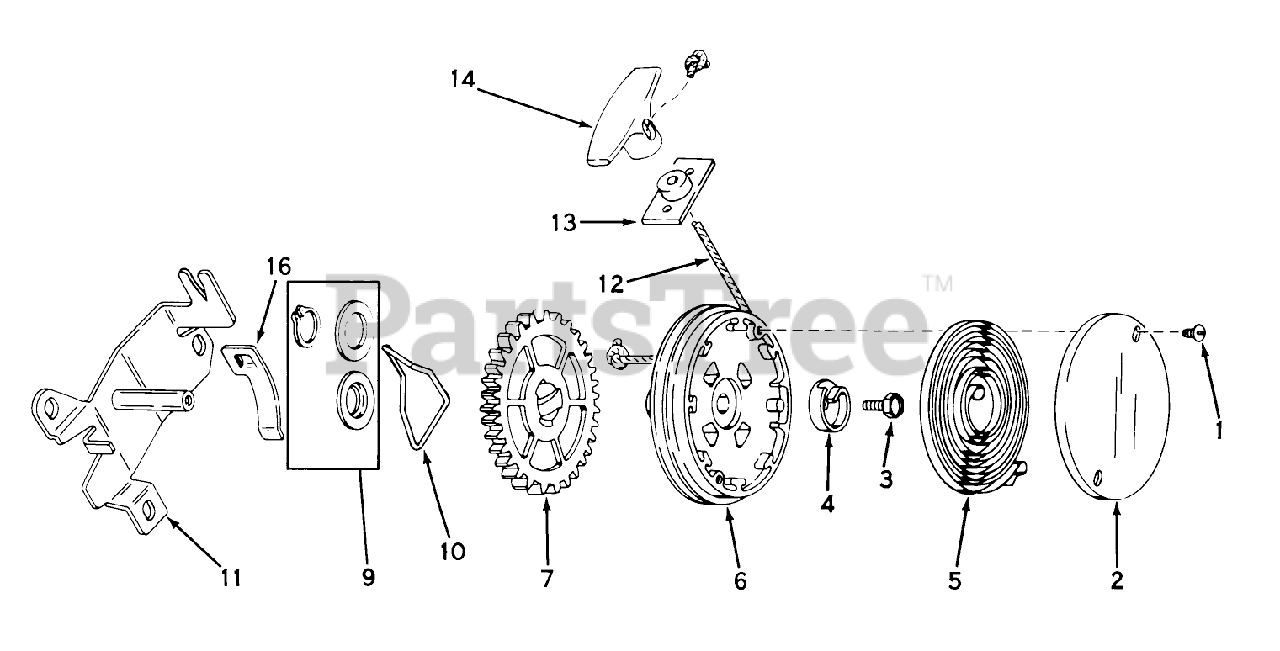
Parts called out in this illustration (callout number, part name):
1	Screw, Cover
2	Cover, Spring
3	Screw, Hex Washer Head
4	Hub Spring
5	Spring, Rewind
6	Pulley Assy. (Incl. No. 9)
9	Kit, Thrust Wash. Snap Rg.
10	Brake
11	Bracket Assy. Mounting
12	Rope, Starter
13	Bracket Assy.
14	Handle-Starter
16	Clip Rope
